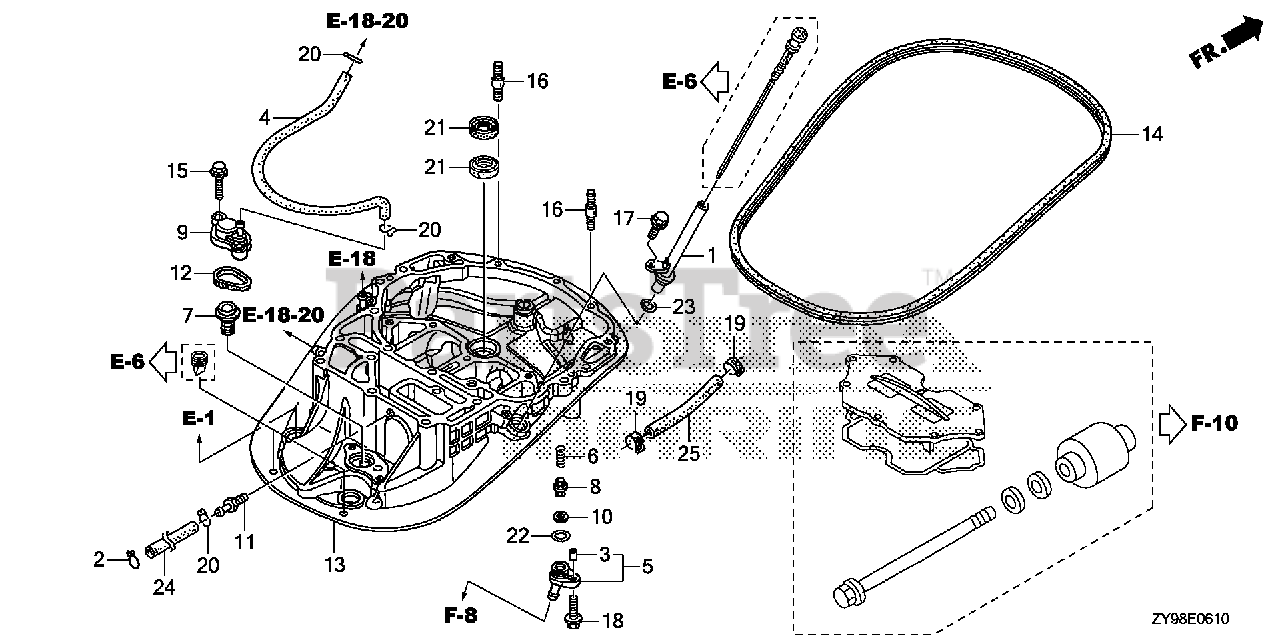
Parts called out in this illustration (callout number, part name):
1	PIPE, OIL LEVEL
2	CLIP, TUBE
3	COLLAR, DISTANCE (6.5X11X7.5)
4	TUBE B, WATER
5	COVER, FLUSH VALVE
6	SPRING, FLUSH VALVE
7	VALVE ASSY., RELIEF
8	VALVE, FLASH
9	COVER, RELIEF VALVE
10	GASKET, FLASH VALVE
11	JOINT, WATER TUBE
12	O-RING, THERMOSTAT COVER
13	CASE, MOUNT *NH8* (DARK GRAY)
14	SEAL A, COVER (LOWER)
15	BOLT, FLANGE (6X22)
16	BOLT, STUD (8X28)
17	BOLT, FLANGE (6X12)
18	BOLT, FLANGE (6X20)
19	CLAMP, TUBE (D10.5)
20	CLIP, TUBE (B10)
21	SEAL, WATER (22X35X7)
22	O-RING (16MM)
23	O-RING (11.5X3.5)
24	TUBE, WATER CHECK
25	BULK HOSE, VACUUM (7X3000) (7X110)
